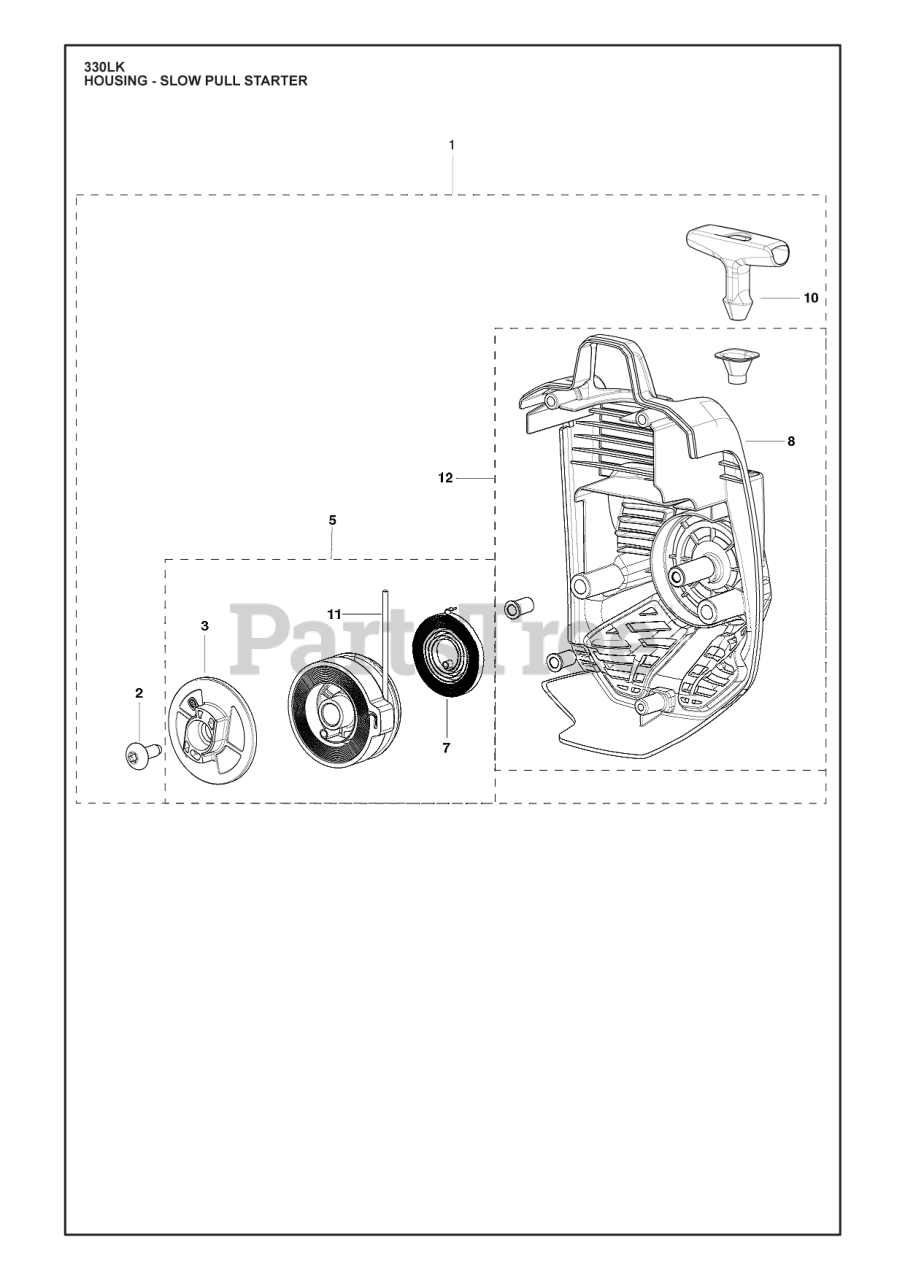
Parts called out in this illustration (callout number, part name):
1	SERVICE KIT 130 TRIMMER START
2	SCREW
3	DRIVER
5	SERVICE KIT 130 TRIMMER START
7	Springs
8	STARTER HOUSING ASSEMBLY
10	STARTER HANDLE
11	KIT ROPE
12	STARTER HOUSING
